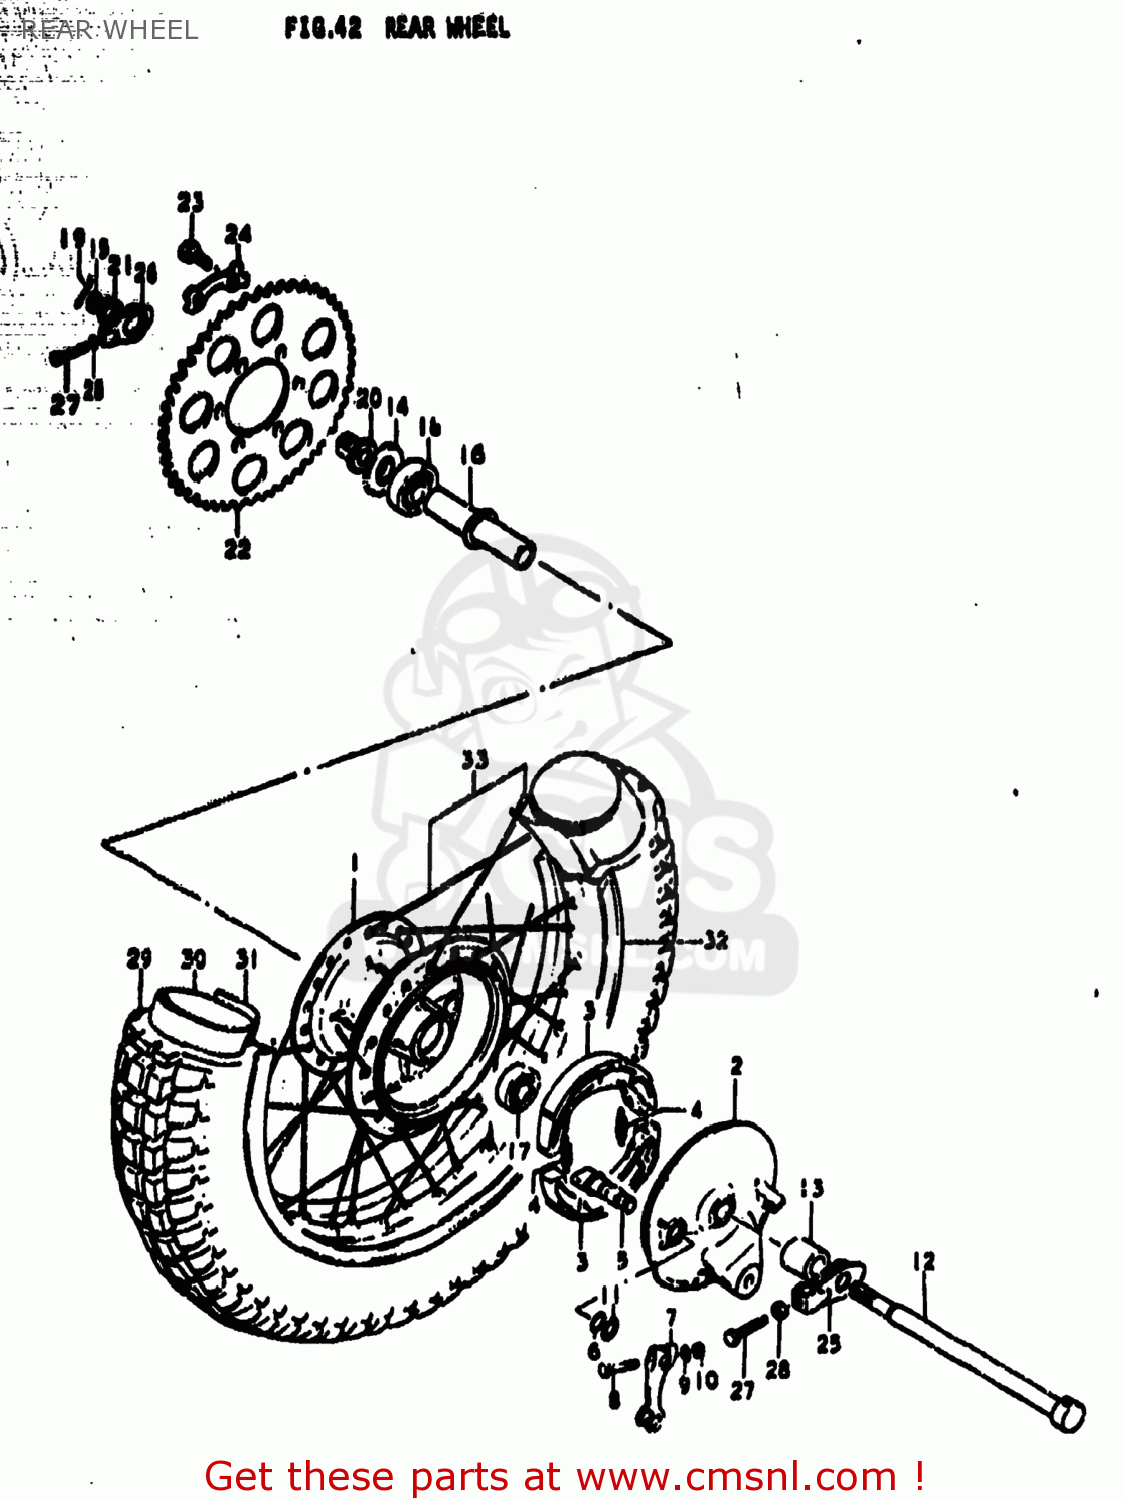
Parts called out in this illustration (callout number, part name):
1	HUB,REAR WHEEL
2	PANEL,REAR HUB
3	SHOE,BRAKE
4	SPRING(L:34)
5	CAM,FR BRAKE
6	O RING(D:2.5,ID:11.4)
7	LEVER,RR BRAKE CAM
8	BOLT
9	WASHER
10	NUT
11	WASHER(12.5X20X1)
12	AXLE,REAR
13	SPACER(15.2X22X26)
14	SPACER,RR AXLE,L
15	NUT 12MM
16	SPACER,RR WHEEL HUB BEARING
17	BEARING
18	BEARING
19	COTTER PIN
20	SPACER,CHAIN ADJUSTER,L
21	NUT
22	SPROCKET,REAR
23	BOLT(8X30)
24	WASHER
25	ADJUSTER,CHAIN
26	ADJUSTER,CHAIN,L
27	BOLT
28	NUT
29	TIRE 3.50-18 089-458MM
30	TUBE ASSEMBLY,WHEEL,INNER
31	PROTECTOR,INNER TUBE
32	RIM,REAR WHEEL
33	SPOKE SET,REAR
